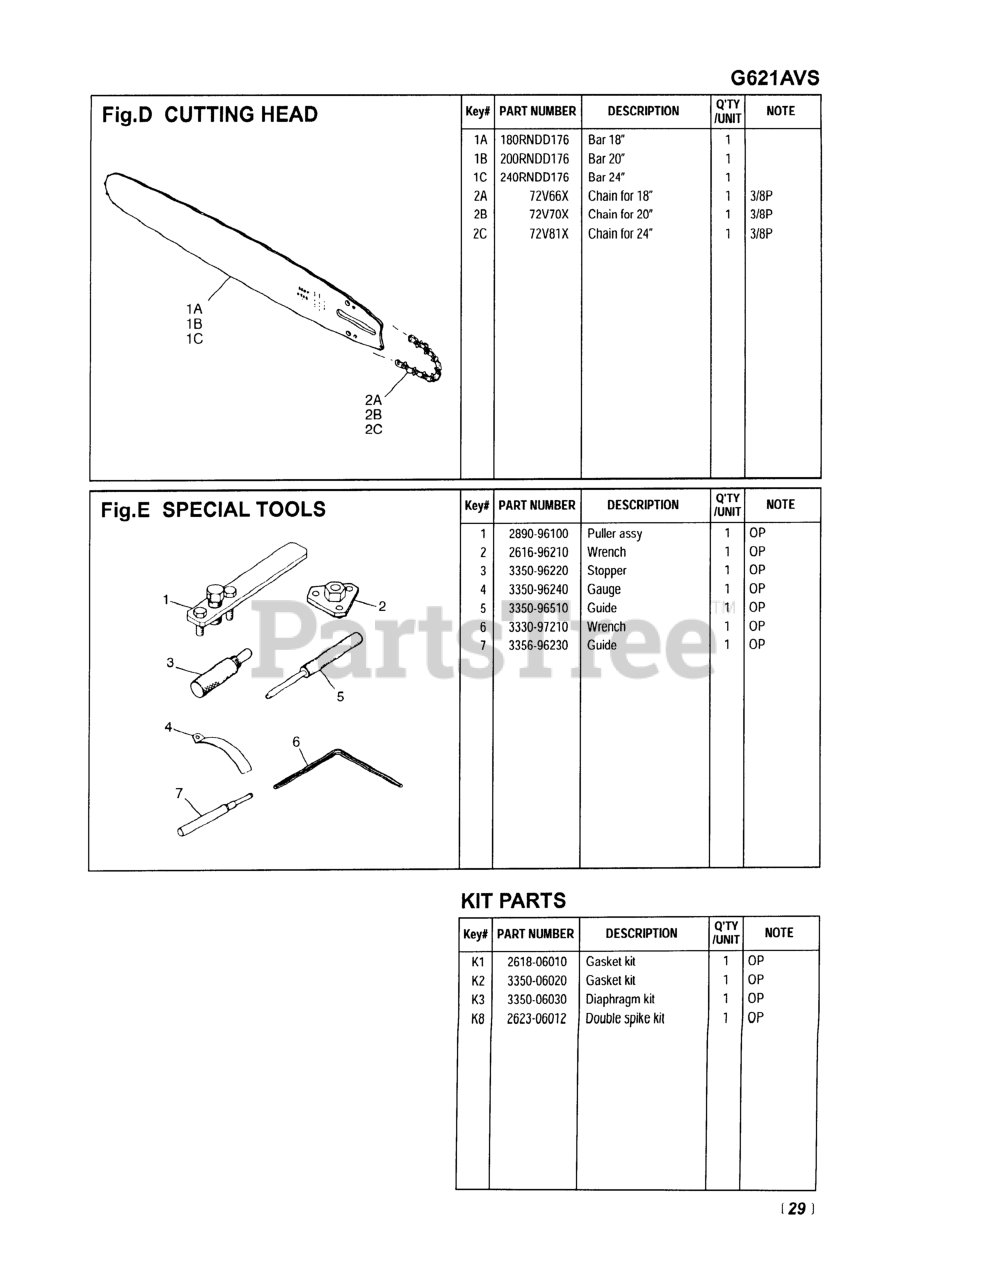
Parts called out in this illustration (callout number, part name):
1	PULLER ASSY
1A	18
1B	20
1C	24
2	WRENCH, CLUTCH (TOOL)
2A	CHAIN FOR 18
2B	CHAIN FOR 20
2C	CHAIN FOR 24
3	STOPPER (TOOL) (RPLS 3320-9641
4	GUAGE, AIR GAP (TOOL)
5	GUIDE, BRAKE SP (TOOL)
6	WRENCH (TOOL)
7	GUIDE (TOOL)
NI	KIT, GASKET
NI	KIT, DIAPHRAGM
NI	DOUBLE SPIKE KIT
